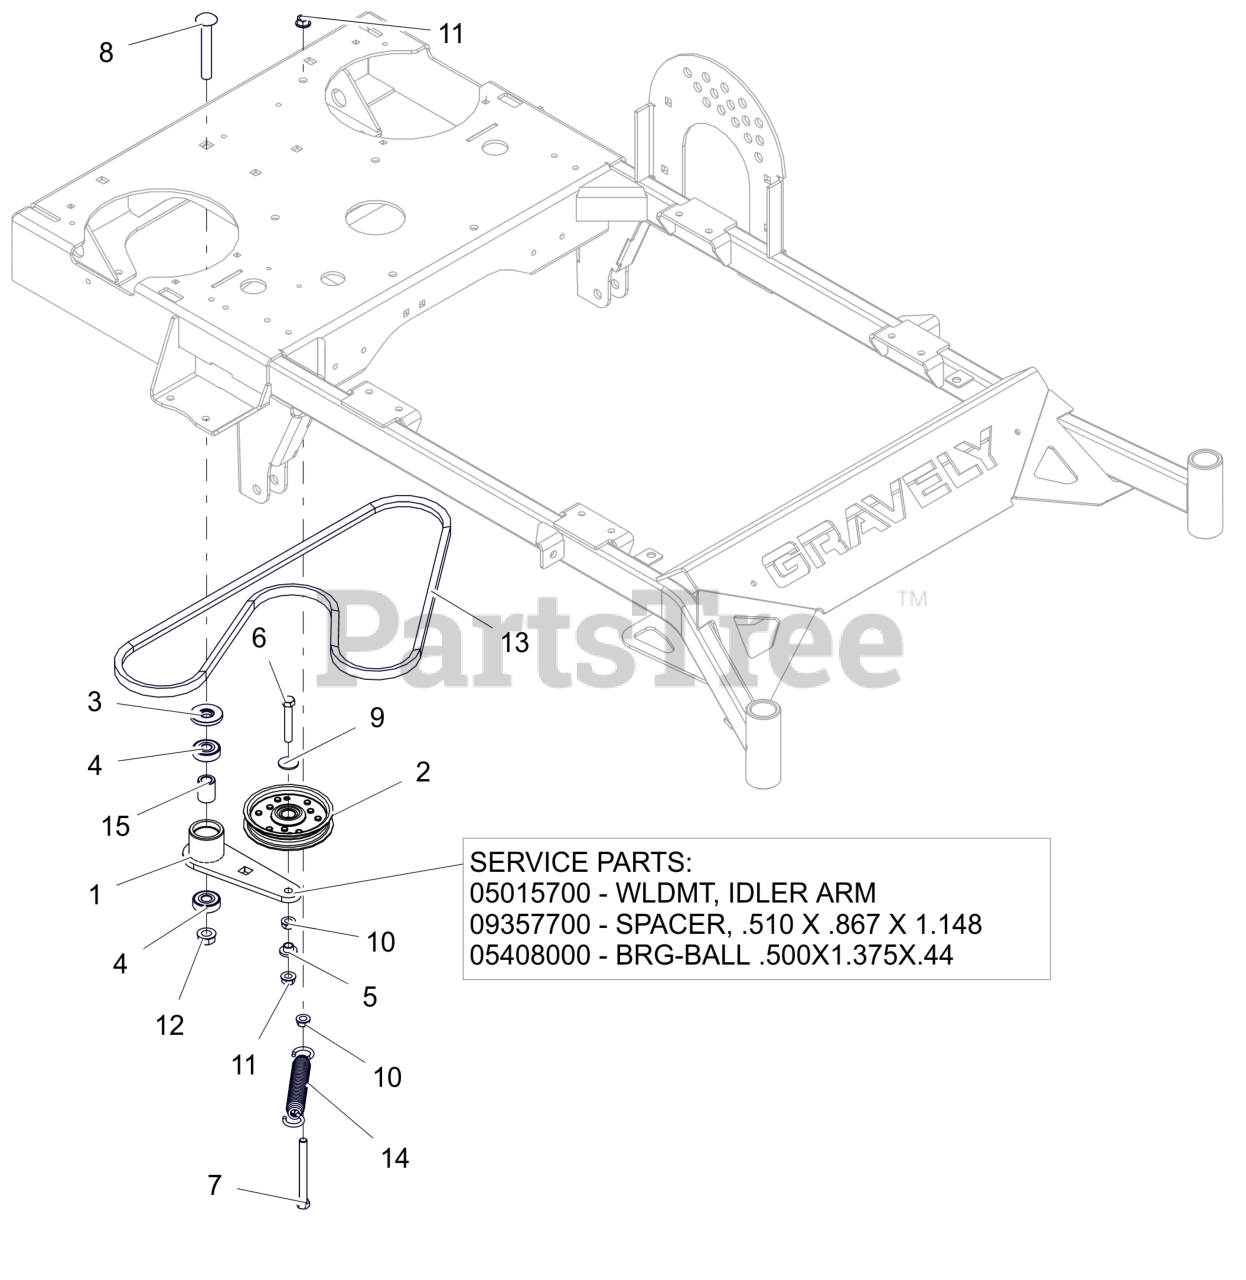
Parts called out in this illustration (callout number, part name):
1	ASM, IDLER ARM SERVICE
1	WELDMENT, IDLER ARM
1	SPACER .510 X .867 X 1.1485
1	BRG-BALL .500X1.38X.437
2	ASM, 4" IDLER (.75 WIDE)
3	SPACER, IDLER ARM
4	BRG-BALL .500X1.38X.437
5	BSHG-FLG .385X.500X.875X.406
6	BLT,HEX .38-16X2.25 G5 ZCC
7	BLT, HEX 0.375-16X3.75 GR5 ZCC
8	BLT, RHSSN .50-13X3.50 G5 ZCC
9	WSHR,FLT .438X1.00X.083 ZCC
10	NUT, SPNLK-FLG .38-16 G5 ZCC
11	NUT-LK-CTR-FLG .375-16 GF ZCC
12	NUT-LK-CTR-FLG .500-13 GG ZCC
13	BELT,HA WRAPPED
14	SPRING- EXTENSION
15	SPACER .510 X .867 X 1.1485
